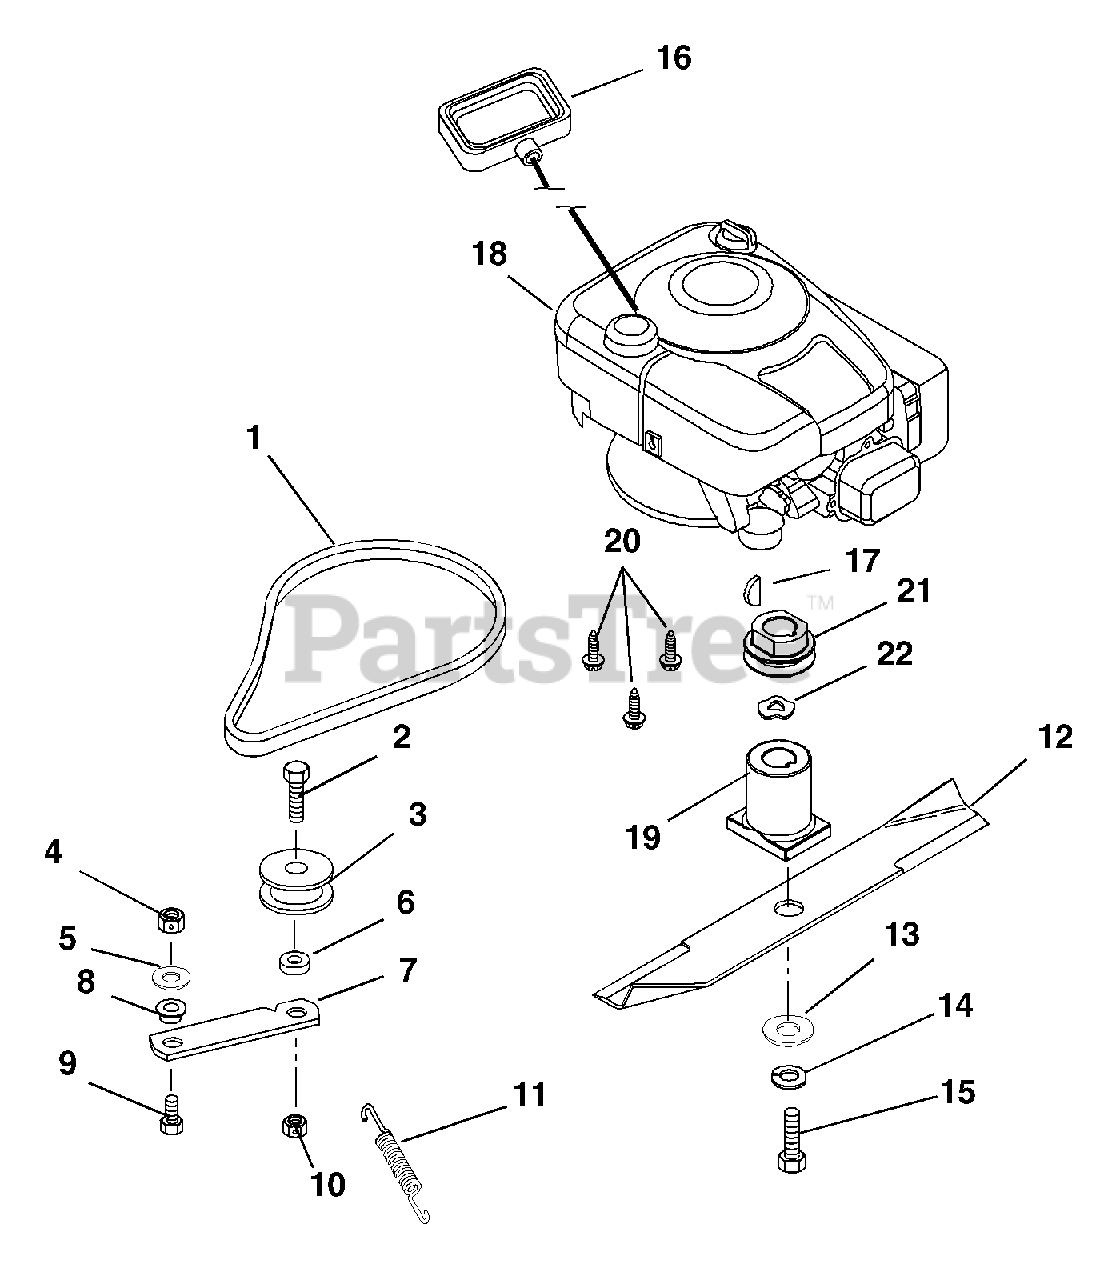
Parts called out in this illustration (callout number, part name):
1	V-Belt 3L Section
2	Bolt-Hex .44-14 x 1.25 Grade 5
3	Idler-Flat 1.75 x .47
4	Nut-Locking-Center .31 -18
5	Washer-Flat-Steel .323 x .625 x .062
6	Bushing-Sleeve .47 x .75 x .43
7	Idler Arm
8	Bushing-Flange .325 x .50 x .25 x 1.12
9	Bolt-Hex .31-18 x .75 Grade 5
10	Nut-Locking-Center .44-14
11	Spring, Tension .043 x .44 x 3.31
12	Blade, 21" Mower
12	Blade, 21" Mower Tungsten
13	Washer-Flat Steel .390 x 1.50 x .125
14	Washer-Locking .38 x .094
15	Bolt-Hex .38-24 x 2.00 Grade 8
16	Recoil Start Handle
17	Key-Woodruff .156 x .625 x .25 SAE #6
18	Engine Briggs & Stratton Intek Pro 6.75
19	Blade Adapter
20	Screw-Tapping .38-16 x 1.00 Hex Washer Head
21	Pulley
22	Washer-Wave .885 x 1.31 x .125
